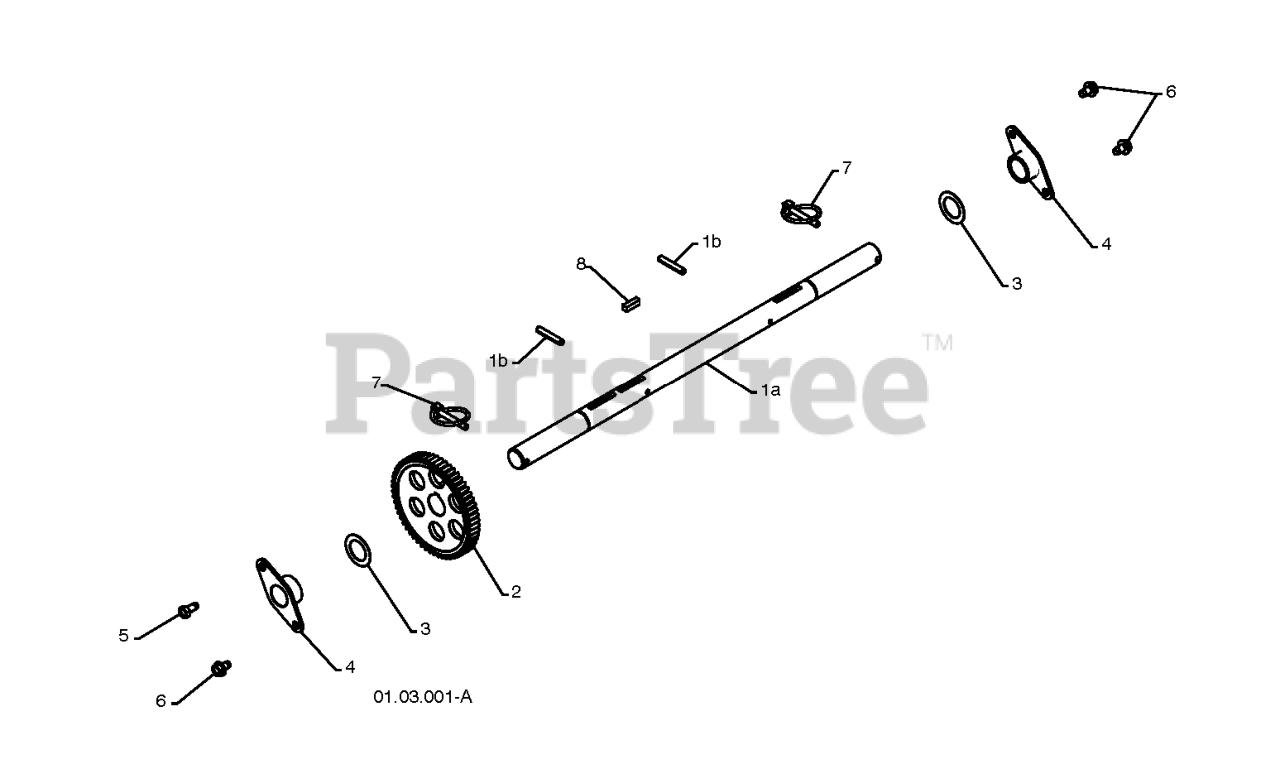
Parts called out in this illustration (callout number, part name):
1	AXLE.ASM.SHAFT.W/ROLLPIN.PS
2	GEAR, AXLE (58T)
3	WASHER TRUST 1"
4	BEARING, AXLE
6	Screw 5/16-18 x 1/2 Hex, Self Tapping 5/16-18 x 1/2
7	PIN KLIK, 1/4
8	KEY, SQUARE 1/4 X .875
